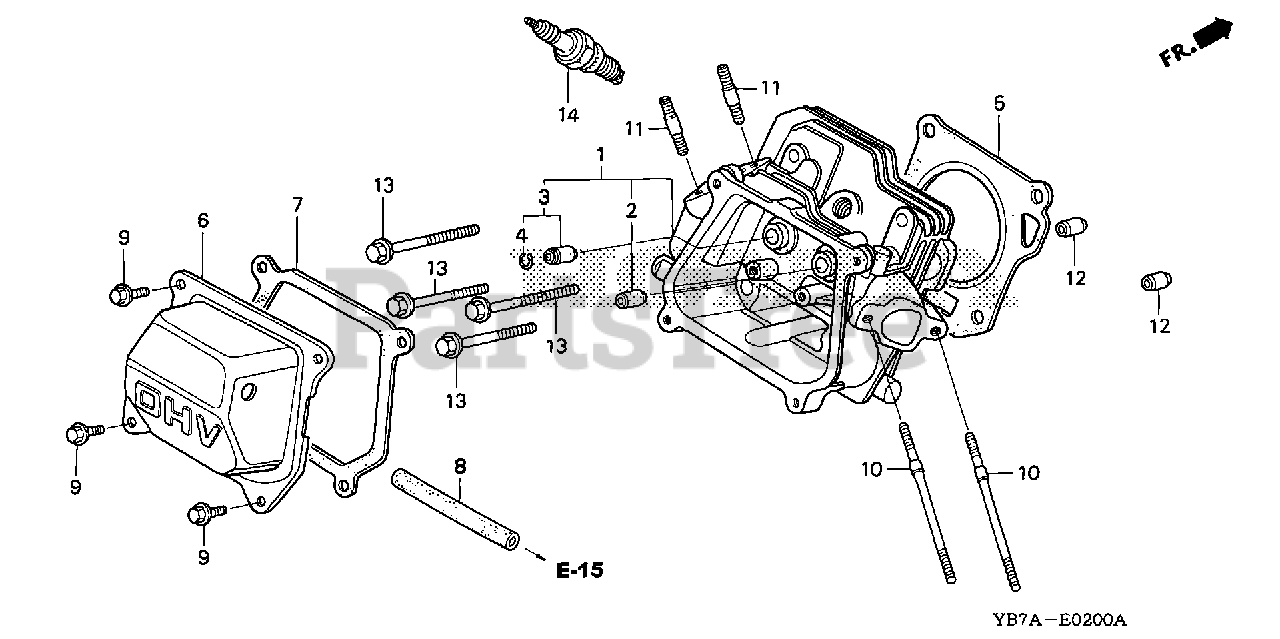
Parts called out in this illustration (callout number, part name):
1	CYLINDER HEAD
2	GUIDE, VALVE (OVER SIZE)
3	GUIDE, EX. VALVE (OVER SIZE)
4	CLIP, VALVE GUIDE
5	GASKET, CYLINDER HEAD
6	COVER, HEAD
7	GASKET, HEAD COVER
8	TUBE, BREATHER
9	BOLT, FLANGE (6X12) (CT200)
10	BOLT, STUD (6X112)
11	BOLT, STUD (8X32)
12	PIN, DOWEL (10X16)
13	BOLT, FLANGE (8X60)
14	SPARK PLUG (BPR6ES) (NGK)
14	SPARK PLUG (W20EPR-U) (DENSO)
